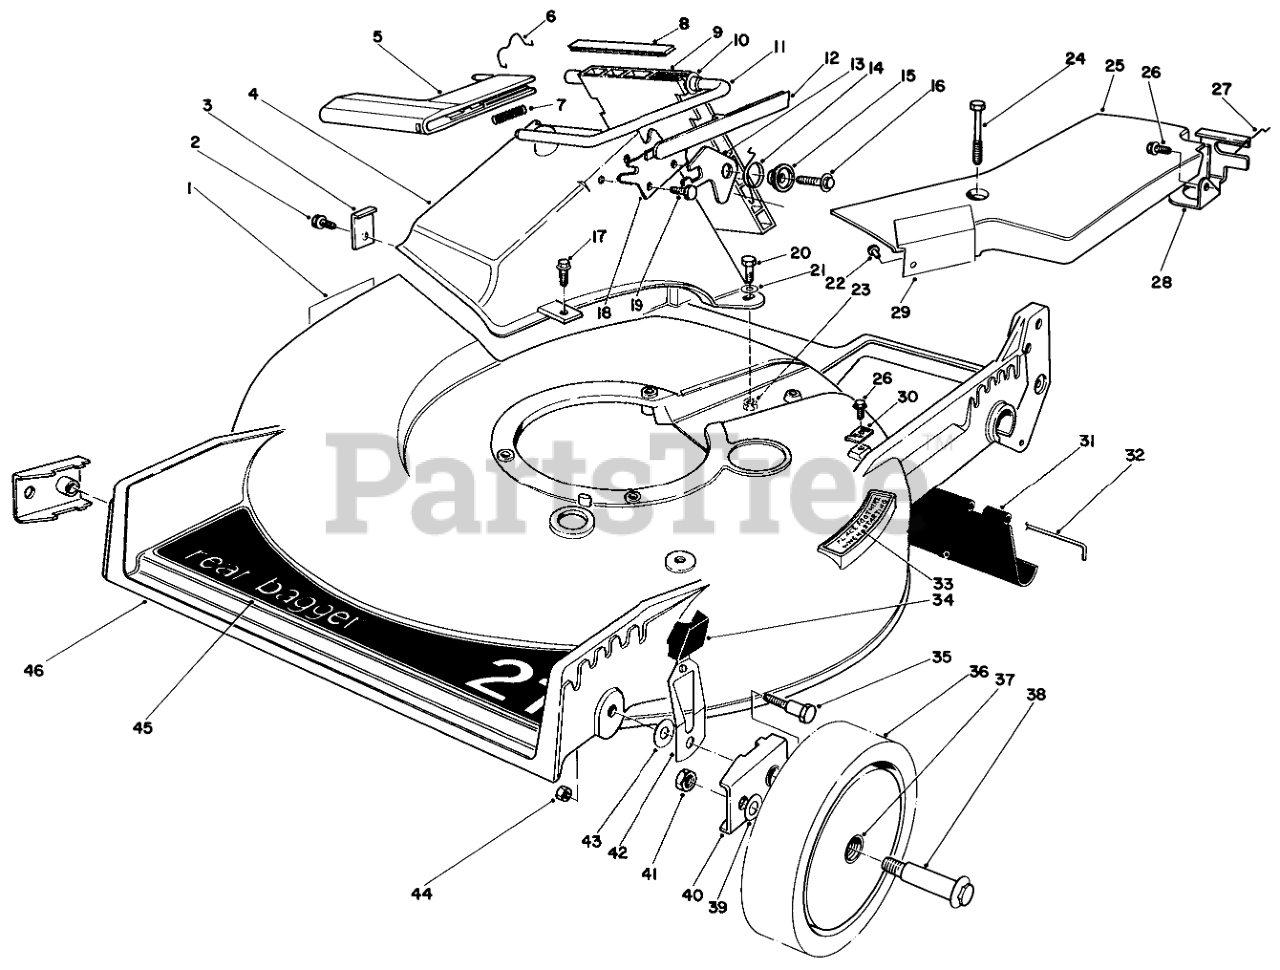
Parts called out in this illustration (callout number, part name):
1	DECAL-DANGER
2	SCREW
3	TUNNEL CLIP
4	Tunnel Discharge
5	Handle-Door
6	DOOR RET SPRING
7	Spring
8	DOOR COVER
9	Door Discharge
10	BUSHING-NYLON
11	DOOR ROD +
12	DOOR HANDLE COVER
13	SAFETY LATCH
14	TORSION SPRING
15	Spacer-Latch
16	SCREW-HWH
17	Screw
18	DOOR LATCH PLATE
19	SCREW-PLASTITE
20	SCREW-HH
21	WASHER-FLAT
22	RIVET-HEAD, FLAT
23	NUT-LOCK, NI
24	SCREW-HHFTF
25	Belt Cover (Incl. Ref. #22 & 29)
26	SCREW-HWHTF
27	RETAINER-CABLE
28	Bracket-Traction Adj.
29	HEAT SHIELD
30	Cable Clamp
31	SHIELD-TRAILING
32	ROD-SHIELD
33	STEP PAD DECAL
34	KNOB-ARM
35	PIVOT SCREW
36	Wheel & Tire Assembly (Incl. Ref. #37)
37	BUSHING
38	BOLT-WHEEL
39	WASHER
40	HP PIVOT ARM ASM
41	Nut
42	Spring Arm
43	WASHER-PIVOT
44	NUT-LOCK, NI
45	DECK DECAL
46	Housing (Incl. Ref. #1 &33)
